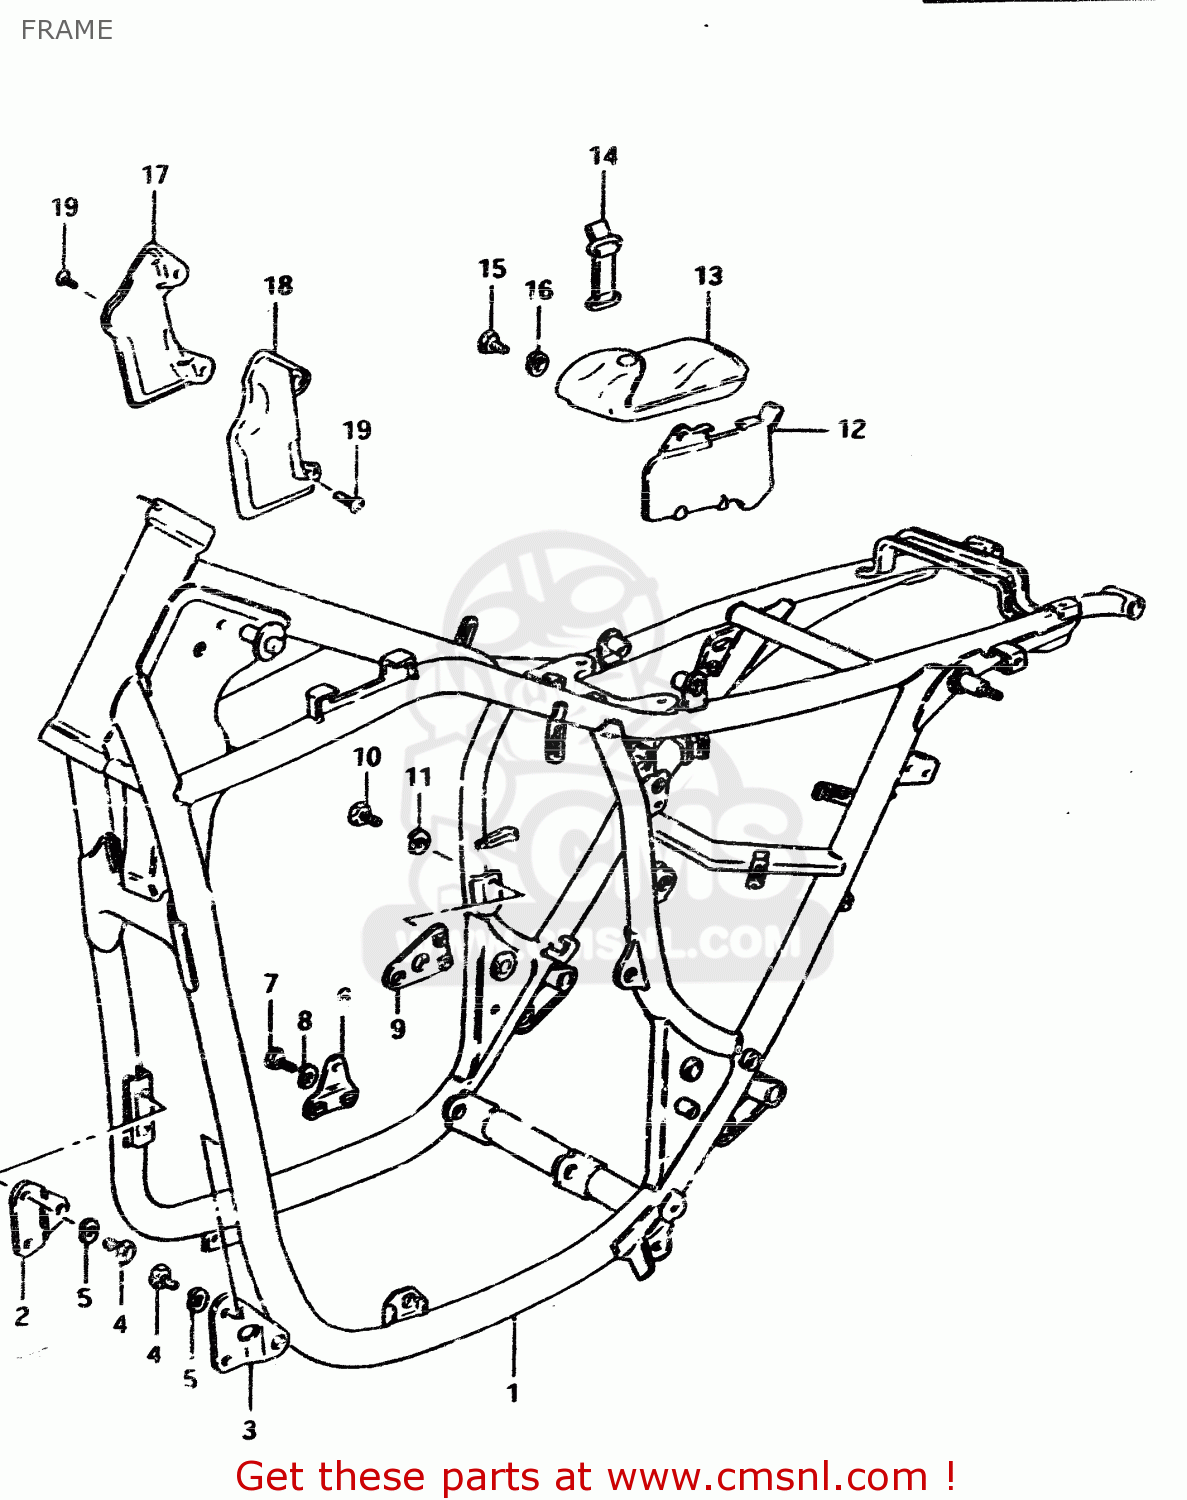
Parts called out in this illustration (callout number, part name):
1	FRAME
2	PLATE,ENG MTG NO.1,R
3	PLATE,ENGINE MOUNTING,LEFT
4	BOLT
5	LOCK WASHER
6	PLATE,MOUNTING NO.2,LEFT
7	BOLT
8	LOCK WASHER
9	PLATE,MOUNTING NO.4,LEFT
10	BOLT
11	LOCK WASHER
12	HOLDER,TOOL
13	TOOL SET
14	BAND
15	BOLT
16	LOCK WASHER
17	COVER,FRAME HEAD,RIGHT
18	COVER,FRAME HEAD,LEFT
19	SCREW M5X12 DIN 7985/N
